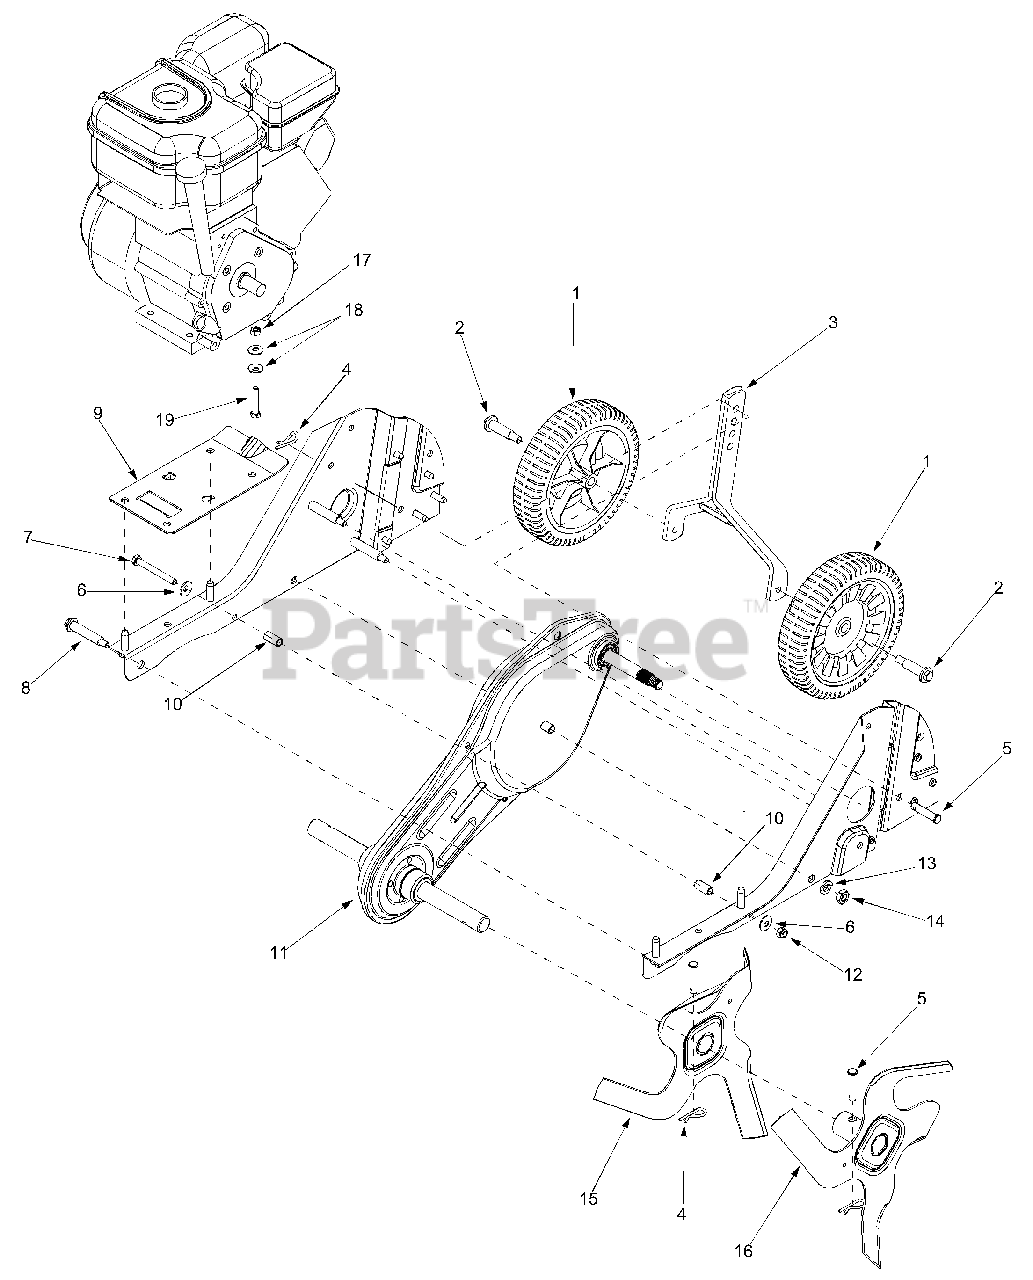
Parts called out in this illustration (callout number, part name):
1	Wheel 8 x 1.75
2	Shoulder Screw
4	Cotter Pin
5	Clevis Pin
6	Bell Washer .340 ID x .872 OD
7	Hex Cap Screw 5/16-18 x 3.0
8	Shoulder Screw
10	Spacer .47 OD x .96Lg
11	Chain Case Assembly
12	Hex Lock Nut 5/16-18
13	Lock Washer 7/16
14	Jam Nut 7/16-20
17	Hex Nut 5/16-18
18	Bell Washer .340 ID x .872 OD
19	Hex Cap Screw 5/16-18 x 1.75
